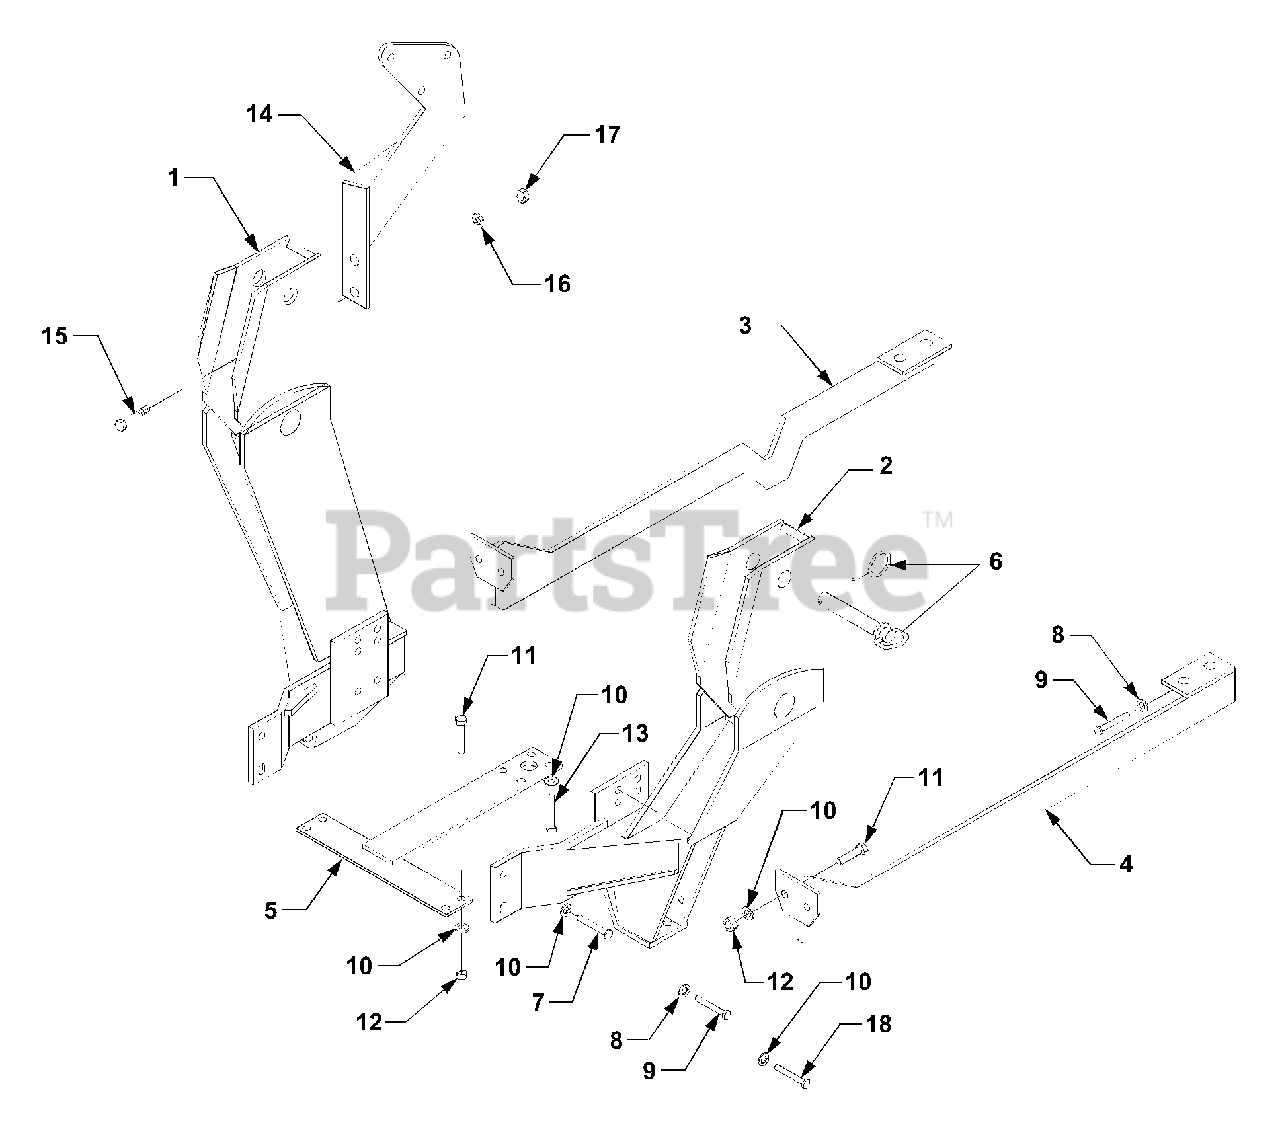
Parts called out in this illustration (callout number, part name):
1	Rear Mount Assembly, RH
2	Rear Mount Assembly, LH
3	Rear Rail Assembly, RH
4	Rear Rail Assembly, LH
5	Rear Cross Member Assembly
6	Latch Pin w/ Linch Pin
7	Hex Cap Screw, 12mm x 60mm
8	Lock Washer, 9/16"
9	Hex Cap Screw, 14mm x 40mm
10	Lock Washer, 1/2"
11	Hex Cap Screw, 1/2" x 1 1/2"
12	Hex Nut, 1/2"
13	Hex Cap Screw, 12mm x 35mm
14	Valve Stand Assembly
15	Hex Cap Screw, 3/8" x 1 1/4"
16	Lock Washer, 3/8"
17	Hex Nut, 3/8"
18	Hex Cap Screw, 12mm x 65mm
